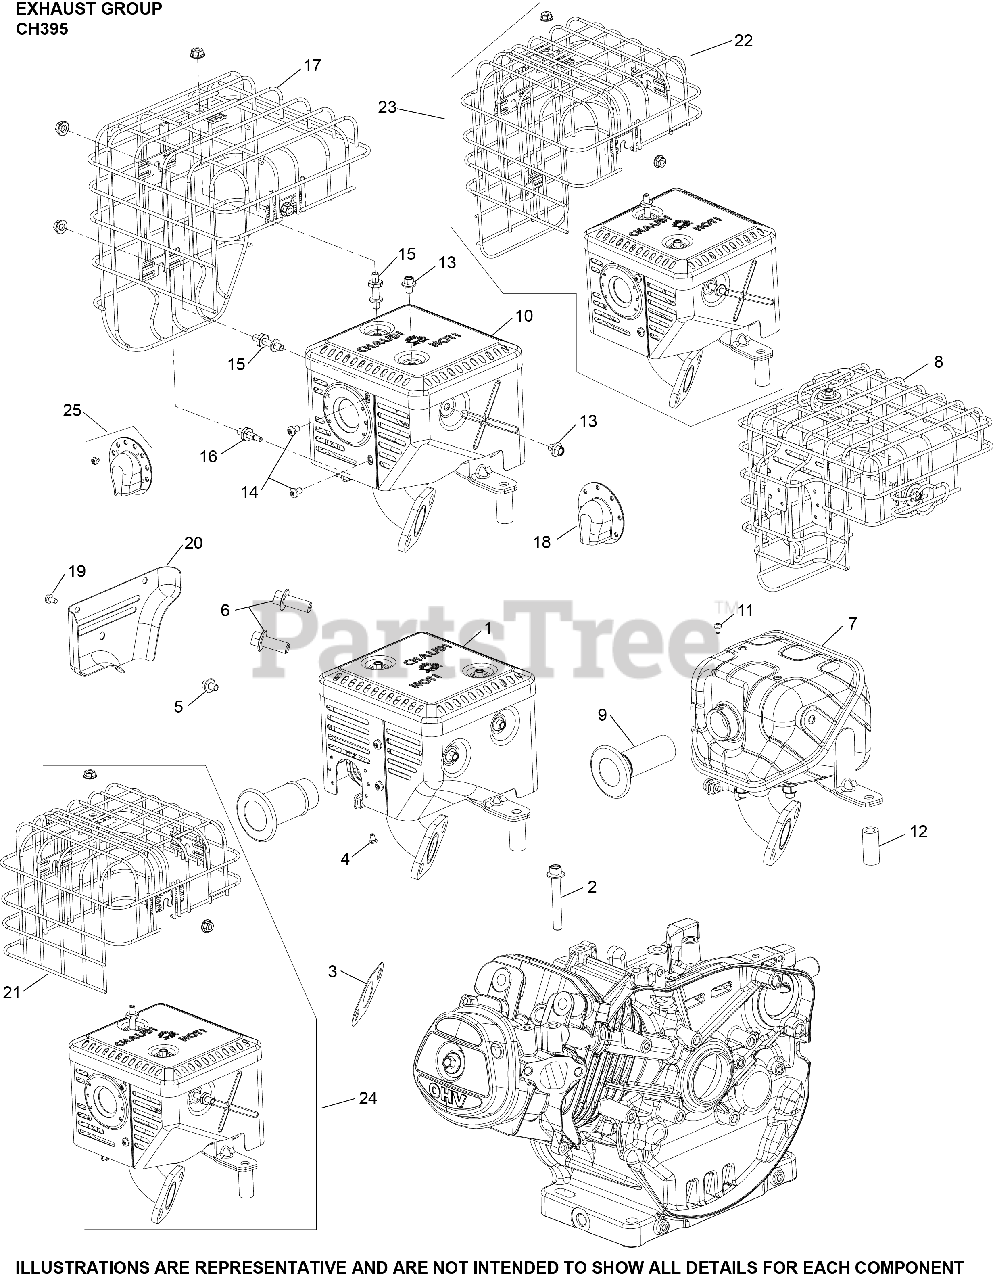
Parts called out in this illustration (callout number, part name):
2	SCREW, M8 X 55
3	GASKET, MUFFLER
6	SCREW, M10 X 25 (CKY)
9	ARRESTOR ASSEMBLY, SPARK
10	MUFFLER ASSEMBLY W/HEAT SHIELD
12	POST, MUFFLER BRACKET
14	SCREW, M5 X 8 (CKY)
